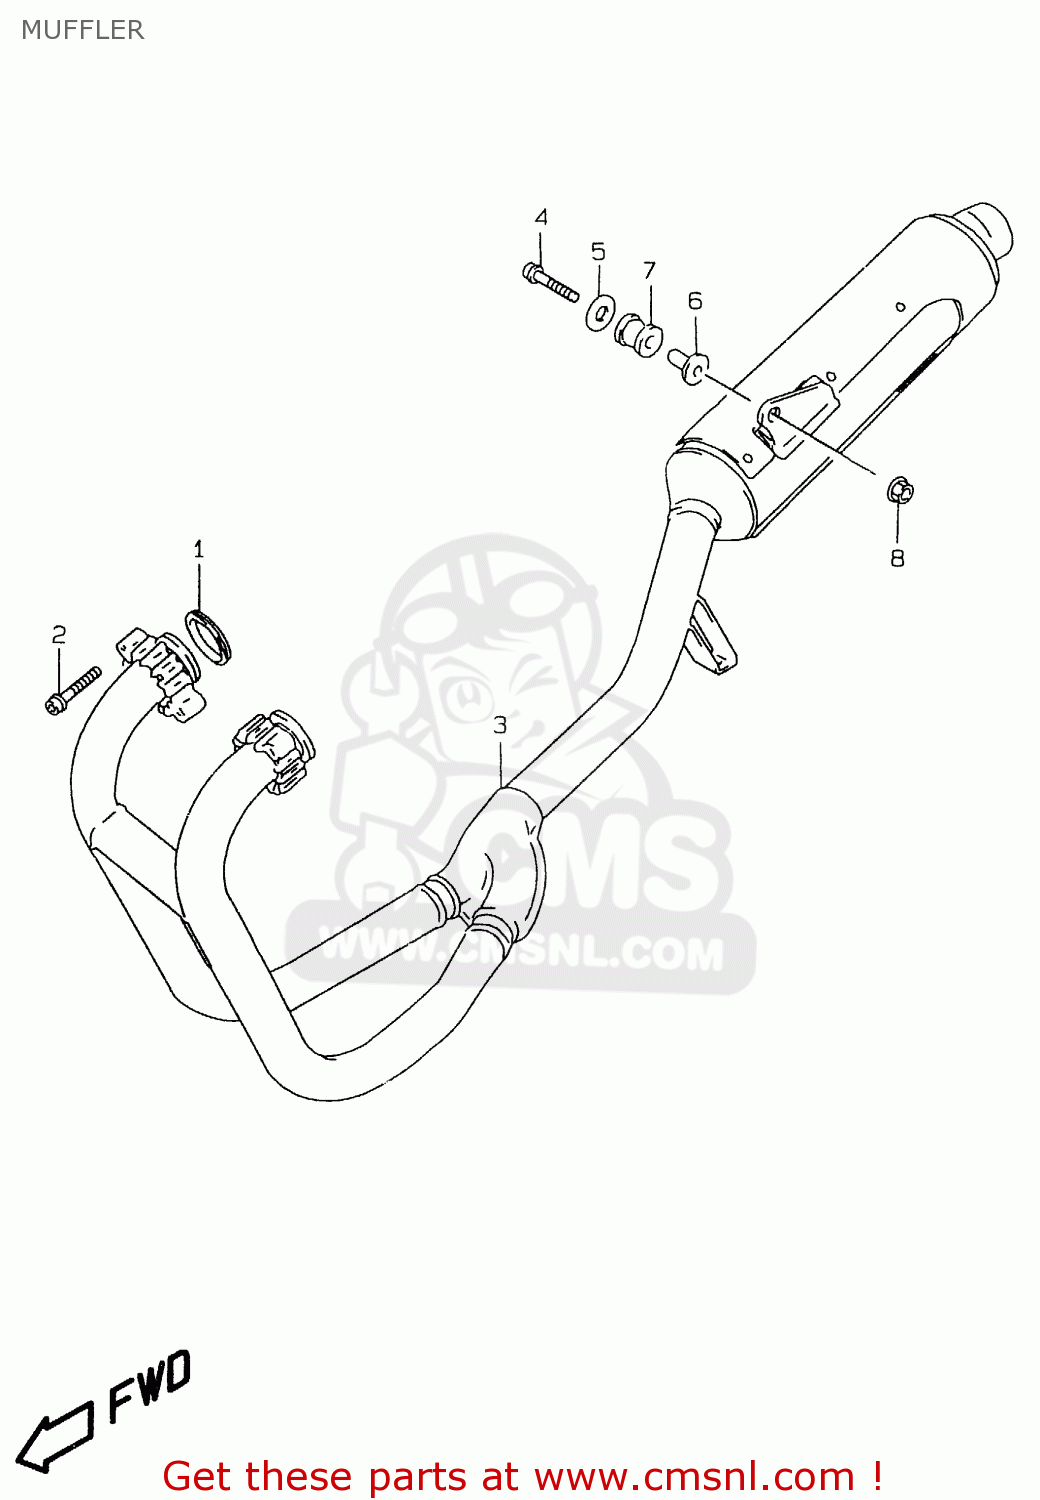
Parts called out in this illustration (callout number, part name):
1	GASKET,EXHAUST PIPE (NAS)
2	BOLT
3	MUFFLER
4	BOLT(8X40)
5	WASHER(8.5X28X1.6)
6	SPACER(8.6X12X24.2)
7	CUSHION
8	NUT
